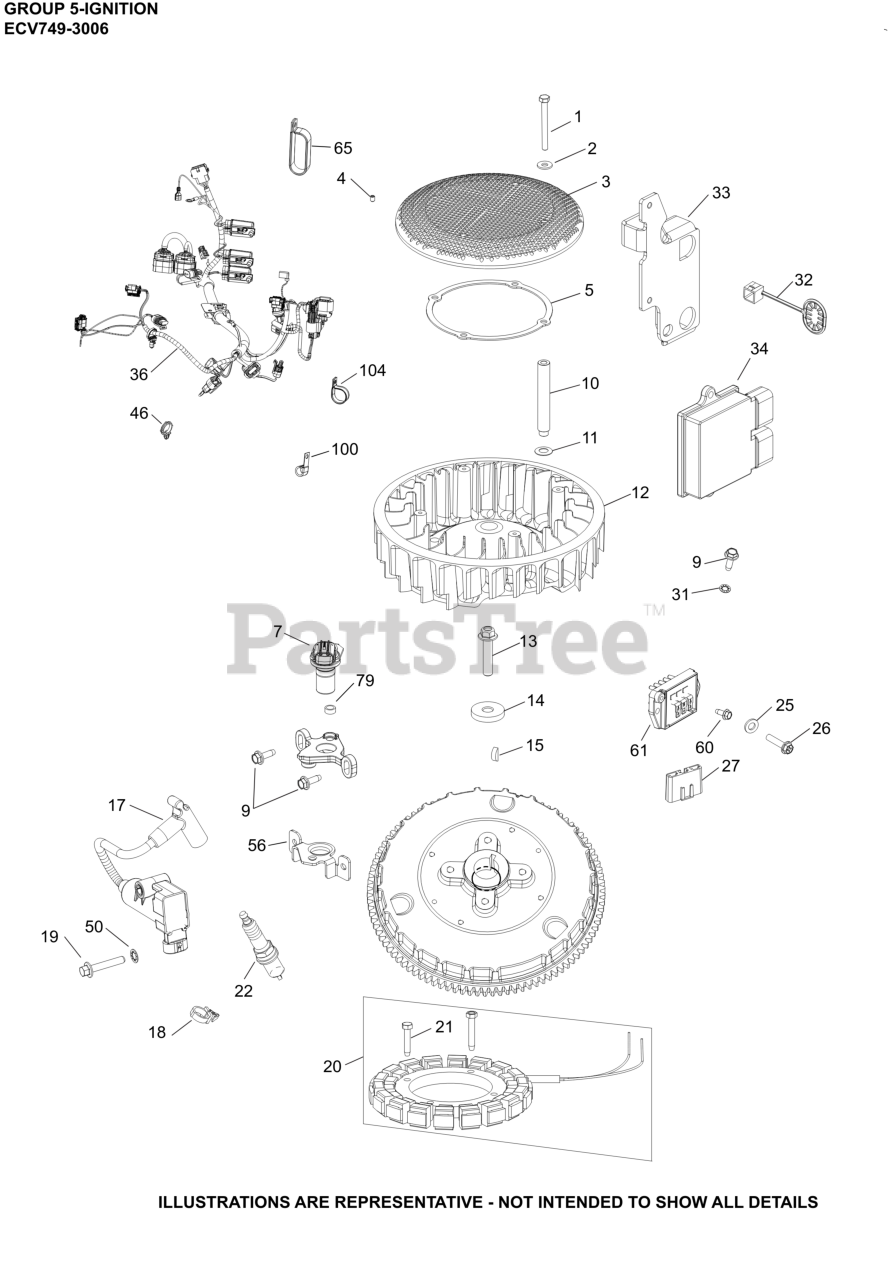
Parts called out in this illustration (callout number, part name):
1	SCREW, CAP M6X1.0X99.5
2	WASHER, FLAT 1/4" (O.D. 5/8")
3	SCREEN, GRASS
4	SCREW, SKT SET #10-24X1/4"
5	RING, SUPPORT
7	SENSOR, SPEED
9	SCREW, THREAD FORMING
11	WASHER, SPRING 10 MM
13	SCREW, HEX FLANGE
14	WASHER, FLAT
15	KEY, 3/16" X 5/8"
17	COIL, IGNITION - EFI
19	SCREW, HEX FLANGE
20	KIT, 15 / 20 AMP STATOR
21	SCREW, THREAD FORMING
22	SPARK PLUG, RFI
25	WASHER, FLAT 1/4" (O.D. 1/2")
26	SCREW, HEX FLANGE HI-LO
27	CONNECTOR
31	WASHER, INT TOOTH LOCK #10
32	CAP, CONNECTOR
33	BRACKET, ECU
34	MODULE, ECU ECV749
36	HARNESS, WIRING ASSEMBLY
46	RETAINER, WIRE HARNESS
50	WASHER, INT TOOTH LOCK 1/4"
56	BRACKET, SENSOR
60	SCREW, THREAD FORMING
61	REGULATOR, RECTIFIER (20-30AMP,FW W/OVP)
65	CLAMP, INSULATED DOUBLE
100	CLIP, CABLE (KM)
104	CLAMP, INSULATED
NI	FLYWHEEL, ASSEMBLY-USE 24 025 115-S
